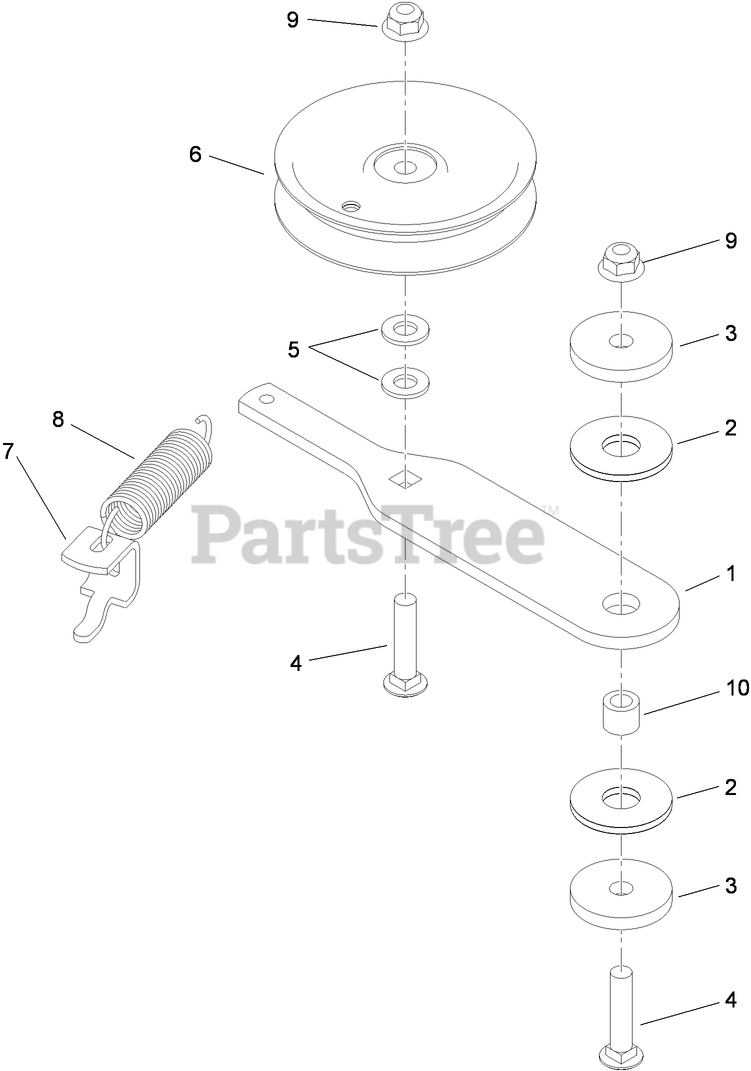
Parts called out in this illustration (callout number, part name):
1	PLATE-IDLER
2	WASHER-FRICTION, COMPOSITE
3	WASHER-PLAIN
4	SCREW-CARR
5	WASHER-FLAT
6	PULLEY-IDLER
7	BRACKET-ANCHOR, SPRING
8	SPRING-EXTENSION
9	NUT-HF, NI
10	BUSHING-LEVER, LIFT
